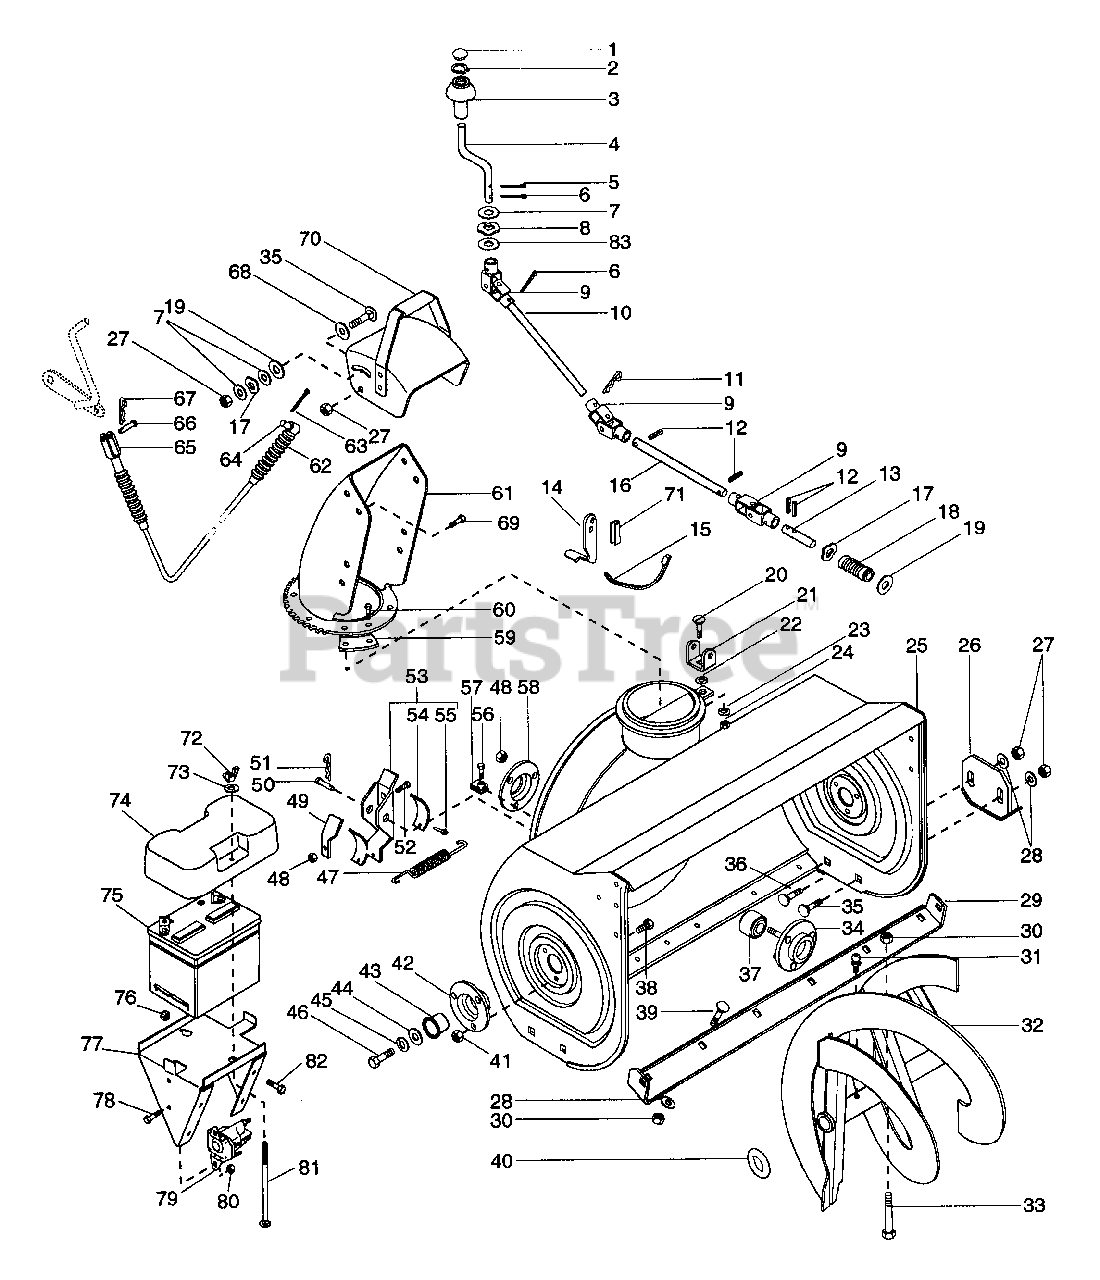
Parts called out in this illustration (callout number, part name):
1	HOLE PLUG
2	RG-RTNG-EXT .375X.010
4	CHUTE CRANK
5	PIN-COTR .12X.75 PL
6	PIN-COTR .12X1.0 PL
7	WSHR-FL-STL.406X.812X.065PL
8	SPRING WASHER
9	UNIVERSAL JOINT ASSEMBLY
10	CHUTE CRANK ROD
11	PIN-HAIR INT .08X.38X1.42 YWZC
12	PIN-ROLL .125X.75
13	WORM SHAFT
14	CHUTE CRANK BRACKET
15	CABLE TIE LG 8-7/8
17	WAVE WASHER .406X.750X.063FH
17	WAVE WASHER .390X.655X.110
18	WORM GEAR L.H.
19	WSHR-PLASTIC .390X.875X.062
20	BLT-RDHDSQNK .31-18X.75 SHT PL
21	WORM CLEVIS
22	WSHR-LK-EXT .375X.035 PL
23	WSHR-LK .313X.062
24	NUT-HEX .312-18
25	BLOWER HOUSING W/DECALS 24
25	BLOWER HOUSING W/DECALS 32
25	BLOWER HOUSING W/DECALS 36
25	BLOWER HOUSING W/DECALS 28
26	RUNNER
26	RUNNER - SKID SHOE
27	NUT-LK-CTR .375-16 GR A PL
28	WSHR-FL-STL .38X.875X.083 PL
29	SCRAPER BLADE 24"
29	SCRAPER BLADE 32"
29	SCRAPER BLADE 28"
29	SCRAPER BLADE 36"
30	NUT-LK .312-18 GR A PL
31	FTG-LUBE .25-28X.256 YWZC
32	RAKE, RIGHT-32"(1ID X 15.75OD)
32	RAKE, LEFT-32"(1"ID X 15.75OD)
32	RAKE, RIGHT-24"(1ID X 14.75OD)
32	RAKE, LEFT-24"(1"ID X 14.75OD)
32	RAKE, RIGHT-28"(1ID X 15.75OD)
32	RAKE, LEFT-28"(1"ID X 15.75OD)
32	RAKE, RIGHT-36"(1ID X 15.75OD)
32	RAKE, LEFT-36"(1"ID X 15.75OD)
33	SHEAR BOLT SERVICE ASSEMBLY
34	BEARING FLANGE
35	BLT-RDHDSQNK .38-16X.75 SHT PL
36	BLT-RDHDSQSHNK .38-16X1.00 PL
37	BRG-BALL1.0X2.0X.56
37	BRG-BALL .750X1.750X.50
38	BLT-SERNK SL .25-20X.50 PL
39	BLT-RDHDSQNK .312-18X.62SHTPL
40	WSHR-FL-STL 1.010X1.505X.062PL
41	NUT-LK-FLG .250-20 PL
42	BEARING SUPPORT
43	BSHG-FLG 1.000X1.12X.62X1.50BR
44	WSHR-FL-STL .511X1.441X.125 PL
45	WSHR-LK .500X.151 HVY PL
46	BLT-HEX .50-13X1.00 PL GR2
47	SG-TENS .062X.56X8.0 WLD 11
48	NUT-LK-CTR .250-20 PL
49	ARM EXTENSION
50	PIN-CLEV .371X1.16 YWZC
51	PIN-COTR .062X.75 PL
52	BLT-HEX .25-20X.63 PL GR2
53	BRAKE ARM ASSEMBLY
54	BRAKE LINING
55	RVT-TBLR .187X.437 RH ST PL
56	BLT-SCRHFWH .38-16X.75 PL
57	NUT-RETNR .38-16 TINRMAN
58	BEARING FLANGE
59	CHUTE CLAMP
60	SCR-TAP 12-24X.50 HWH PL TR
61	DISCHARGE CHUTE - HIGH
61	DISCHARGE CHUTE
62	CONTROL CABLE
63	PIN-COTR .09X.75 PL
64	PIVOT
65	CLEVIS
66	CLEVIS PIN
67	PIN-COTR .06X.50
68	WSHR-FL-STL .520X.810X.033
69	BLT-HEX .38-16X.75 PL GR2
70	CHUTE DEFLECTOR W/DECAL
70	DEFLECTOR W/DECAL
72	NUT-WING .250-20 YWZC
73	WSHR-FL-STL.281X.62X.065 PL
74	COVER, BATTERY
75	BATTERY
76	NUT-LK-FLG .250-20 PL
77	TRAY, BATTERY
78	BLT-HEX .25-20X.63 PL GR2
79	SOLENOID
80	NUT-LK-CTR .250-20 PL
81	BLT-RDHDSQNK .25-20X7.00
82	BLT-HEX .25-20X.75 PL GR2
83	WSHR-FL-STL .382X.812X.023 PL
